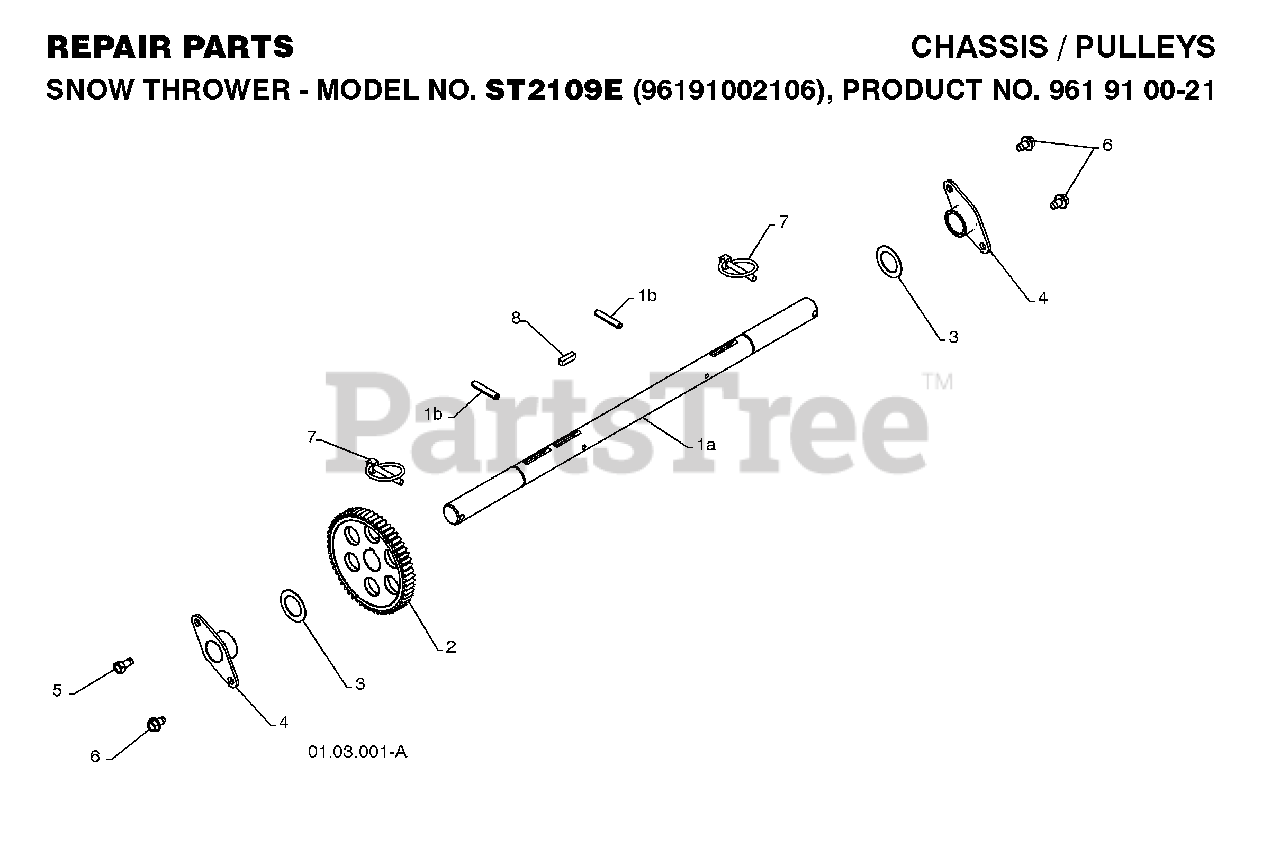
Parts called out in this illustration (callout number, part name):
1A	SHAFT.AXLE.POWER.STEERING
1B	PIN.ROLL.3/16
2	GEAR, AXLE (58T)
3	WASHER TRUST 1"
4	BEARING, AXLE
7	PIN KLIK, 1/4
8	KEY, SQUARE 1/4 X .875
